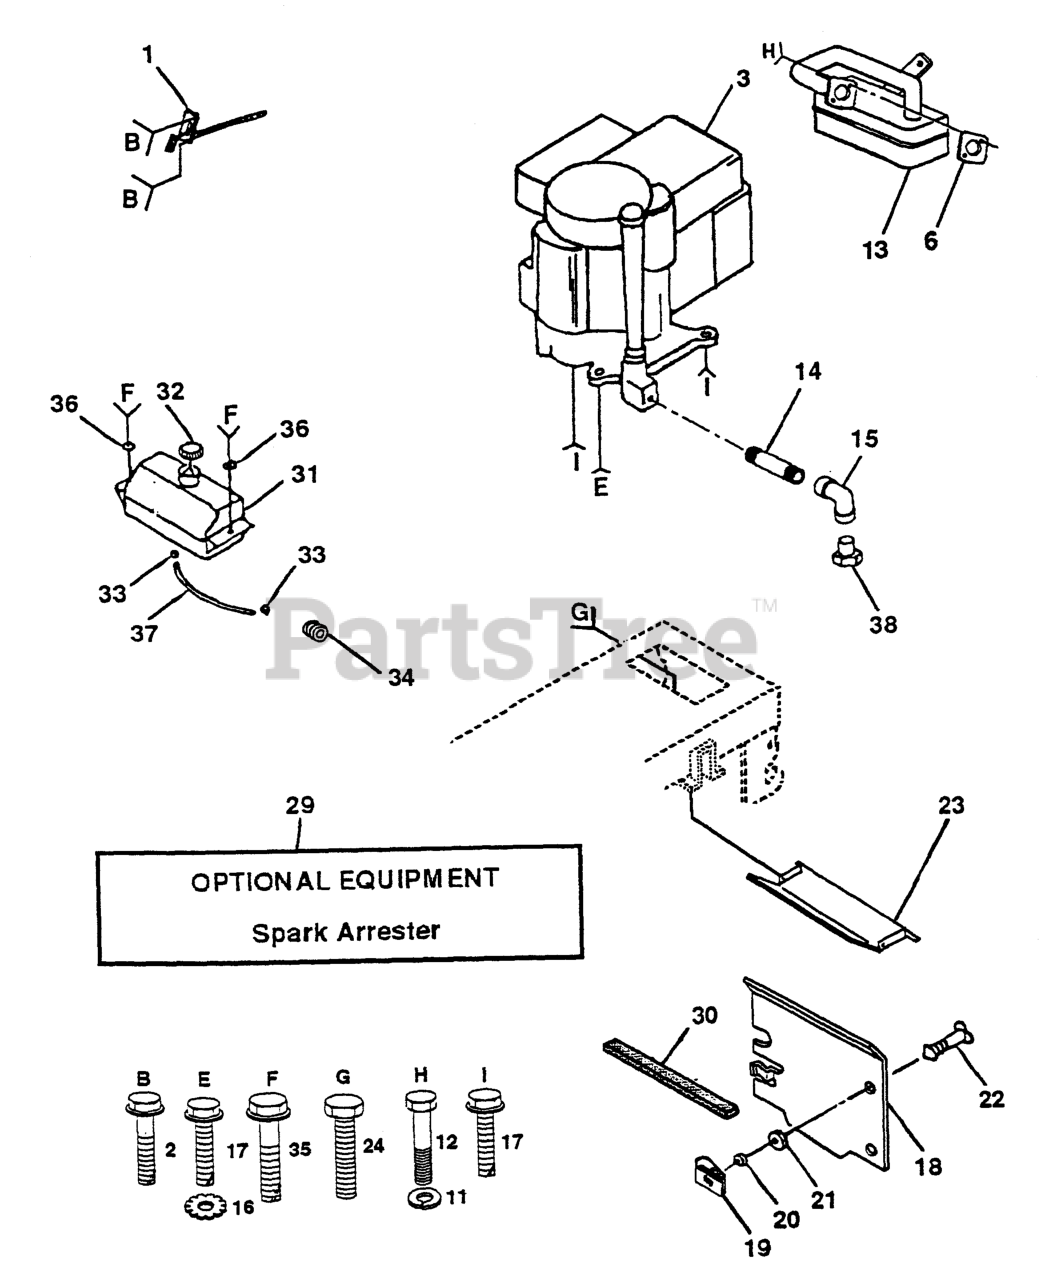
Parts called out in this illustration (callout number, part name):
1	CHOKE CONTROL
2	SCREW LT
3	Engine B&S 12.5 ICQ IVT Dual
6	GASKET ENGINE
11	WASHER.LOCK.HVY.HLCL.SPR.5/16
12	SCREW
13	MUFFLER.SINGLE.B&S.10-12HP
14	Nipple Pipe 3/8 Npt X 3"
15	ELBOW
16	LOCKWASHER
17	SCREW
18	HEAT SHIELD
19	RECEPTACLE LT
20	RETAINER LT
21	WASHER
22	STUD 1/4 TURN
23	HEAT SHIELD
29	KIT.SPARK ARRESTOR 794945 B&S
31	FUEL TANK
32	FUEL CAP
33	HOSE CLAMP
34	BUSHING.SNAP.NYL.BLK.
35	SCREW HEX CRT
36	WASHER
37	LINE.FUEL.20
38	Plug Oil Drain
